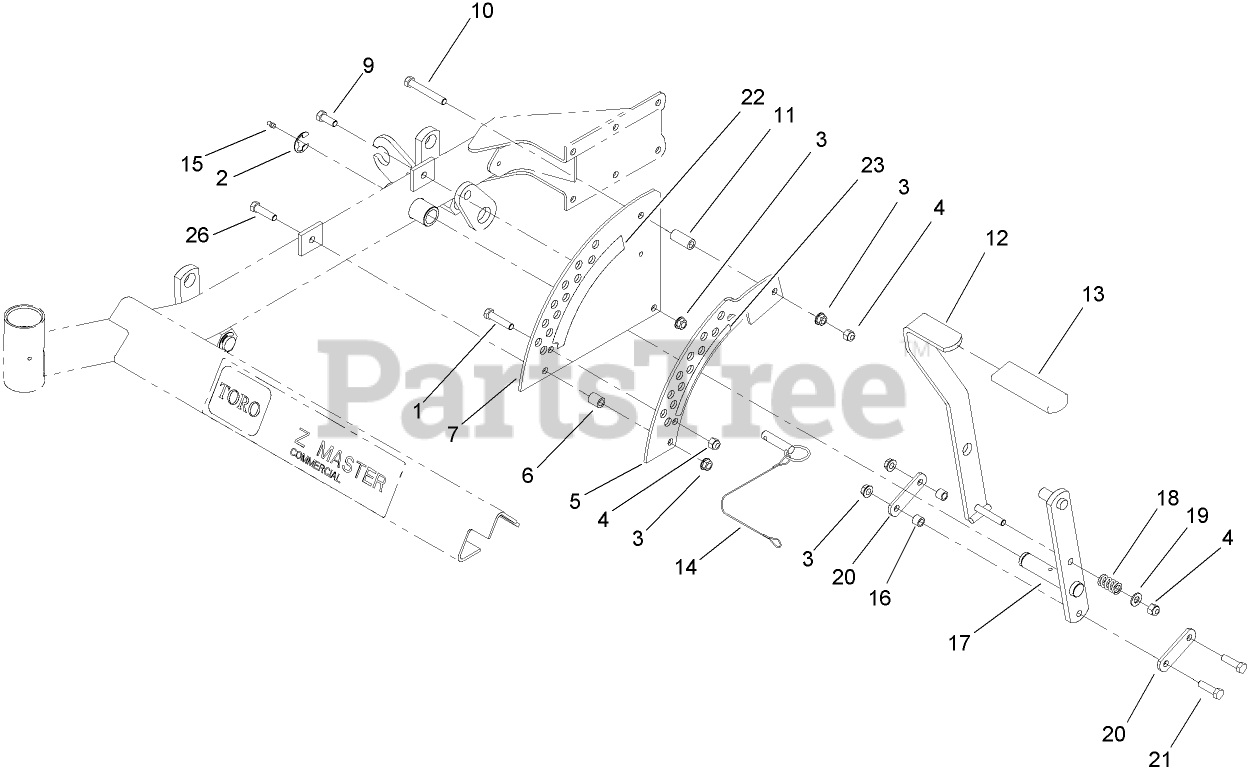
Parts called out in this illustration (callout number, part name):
1	SCREW-HH
2	RING-RETAINING, EXT
3	NUT-HHF, WHIZ
4	NUT-LOCK, NI
5	PLATE-LIFT, DECK
6	BUSHING-LEVER, LIFT
7	PLATE-LIFT, DECK
9	SCREW-HH
10	SCREW-HH
11	BUSHING-LEVER, LIFT
12	HANDLE-LIFT
13	GRIP-LEVER, LIFT
14	Hitch Pin ASM
15	FITTING-GREASE
16	Bushing
17	LIFT ARM ASM
18	SPRING-COMPRESSION
19	WASHER-FLAT
20	ARM-LIFT, DECK
21	SCREW-HH
22	DECAL-DECK HEIGHT, OUTER
23	DECAL-DECK HEIGHT, INNER
26	SCREW-HH
